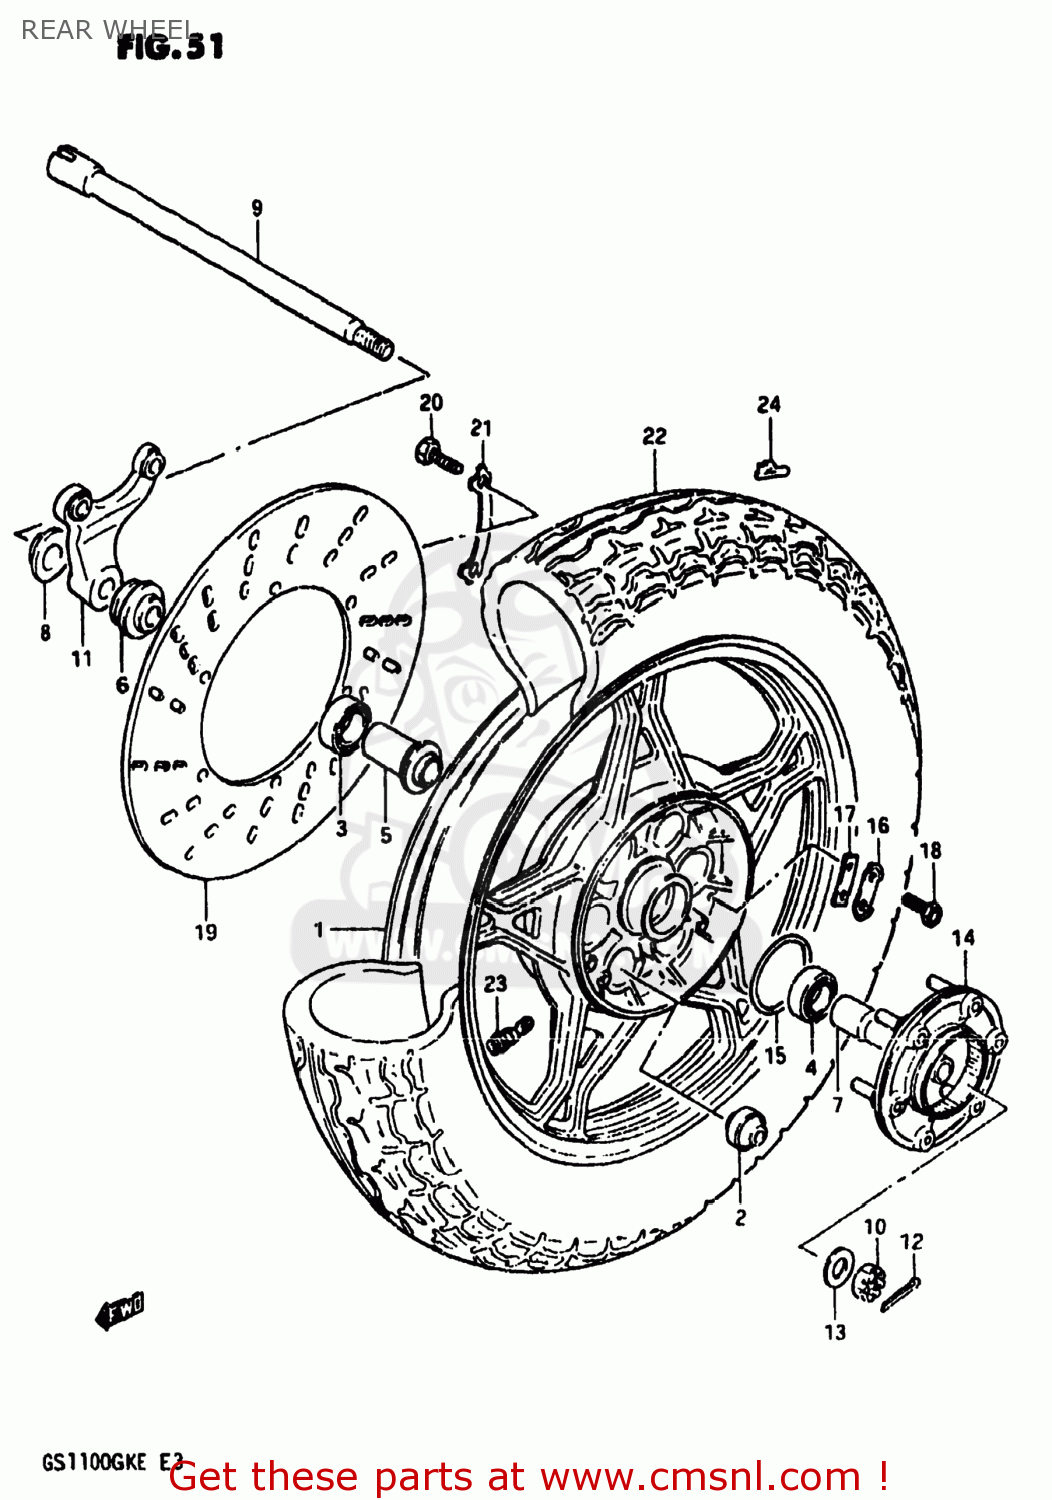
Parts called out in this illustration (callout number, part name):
1	CASTING WHEEL,REAR
2	BUSH
3	BEARING
4	BEARING
5	SPACER,REAR HUB BEARING
6	SPACER,REAR AXLE
7	SPACER,REAR AXLE,LEFT
8	SPACER,REAR AXLE,RIGHT
9	AXLE,REAR
10	NUT
11	BRACKET,RR,CALIPER
12	PIN,COTTER
13	WASHER (17.5X36X3.2)
14	JOINT ASSEMBLY,REAR HUB DRUM
15	O RING(D:2.1,ID:65)
16	WASHER
17	WASHER,THRUST(T:1.6)
18	BOLT(6X16)
19	DISC,RR BRAKE
20	BOLT(8X25)
21	WASHER
22	TIRE
23	VALVE ASSEMBLY,WHEEL RIM,J
24	BALANCER,WHEEL
